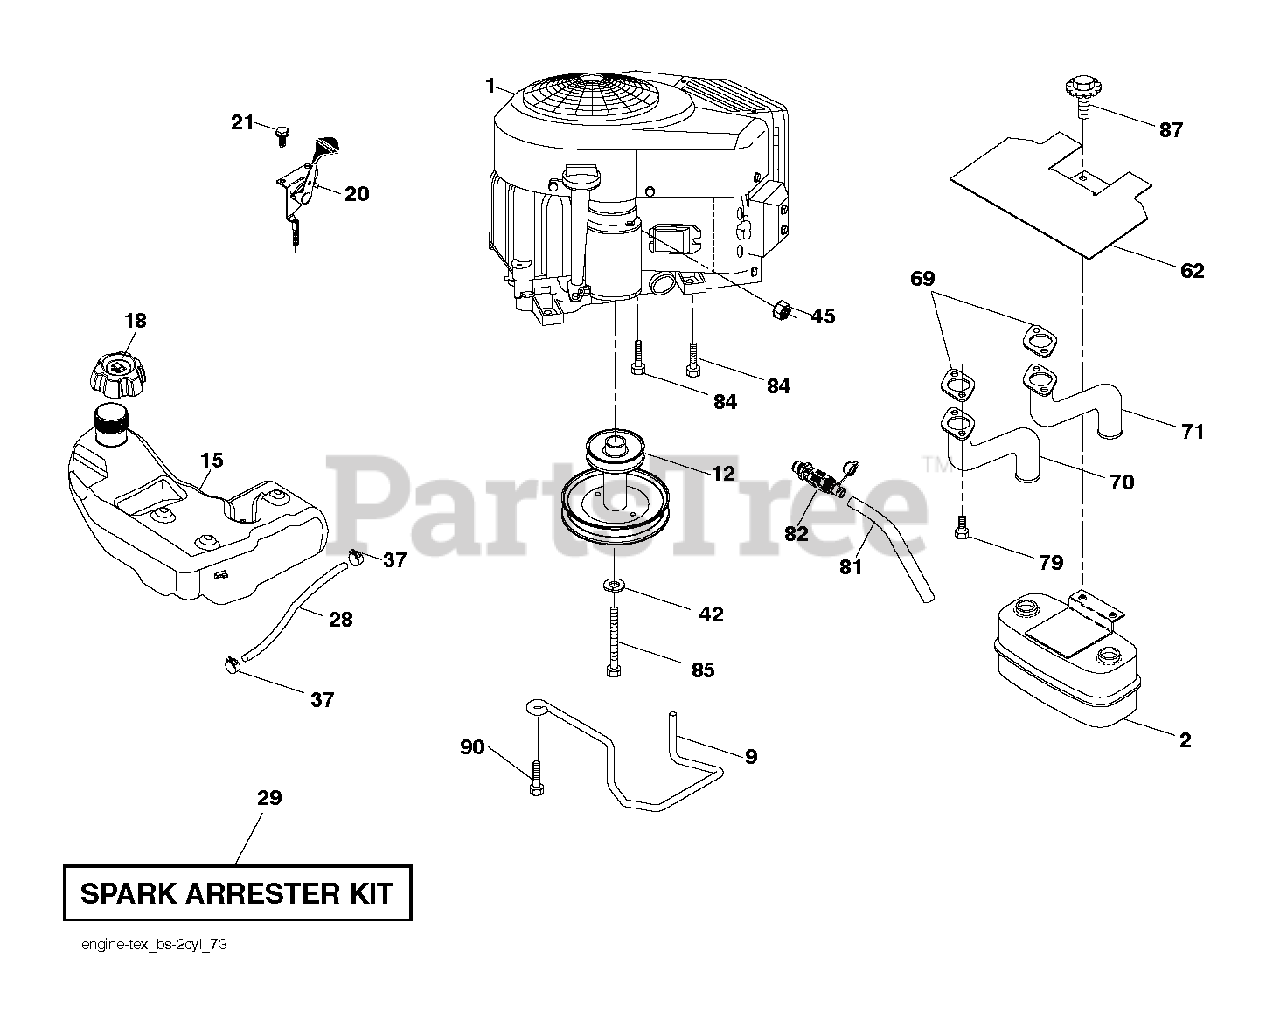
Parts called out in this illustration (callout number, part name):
2	MUFFLER.TWIN.CYL.LOW.TONE
9	KEEPER.BELT.ENGINE.4.2
12	PULLY ENGINE
15	TANK.ASM.FUEL.FR.2.5GA.
18	CAP ASM.FUEL.2.25"FR.
20	CONTROL.TH/CK.COBRA.B&S.TWN.
21	SCREW.#10 X 0.750.BOS (2 2)
28	LINE.FUEL.20"FRONT.EMI
29	KIT.SPARK ARRESTOR(392390 B&S)
37	HOSE CLAMP
42	LOCKWASHER
45	NUT
62	SHIELD.HEAT.MUFFLER
69	GASKET.MUFFLER
70	RP.EXHAUST.TUBE.LH.BS/TWIN
71	RP.EXHAUST.TUBE.RH.BS/TWIN
79	SCREW.SOCKET.HEAD.5/16-18
81	TUBE, DRAIN OIL ASM.
82	VALUE.OIL.DRAIN
84	SCREW.3/8-16
85	BOLT HEX 7/16-20X4-1/4"
87	BOLT, 5/16-18 X 1 3/4
90	SCREW 3/8-16X1
